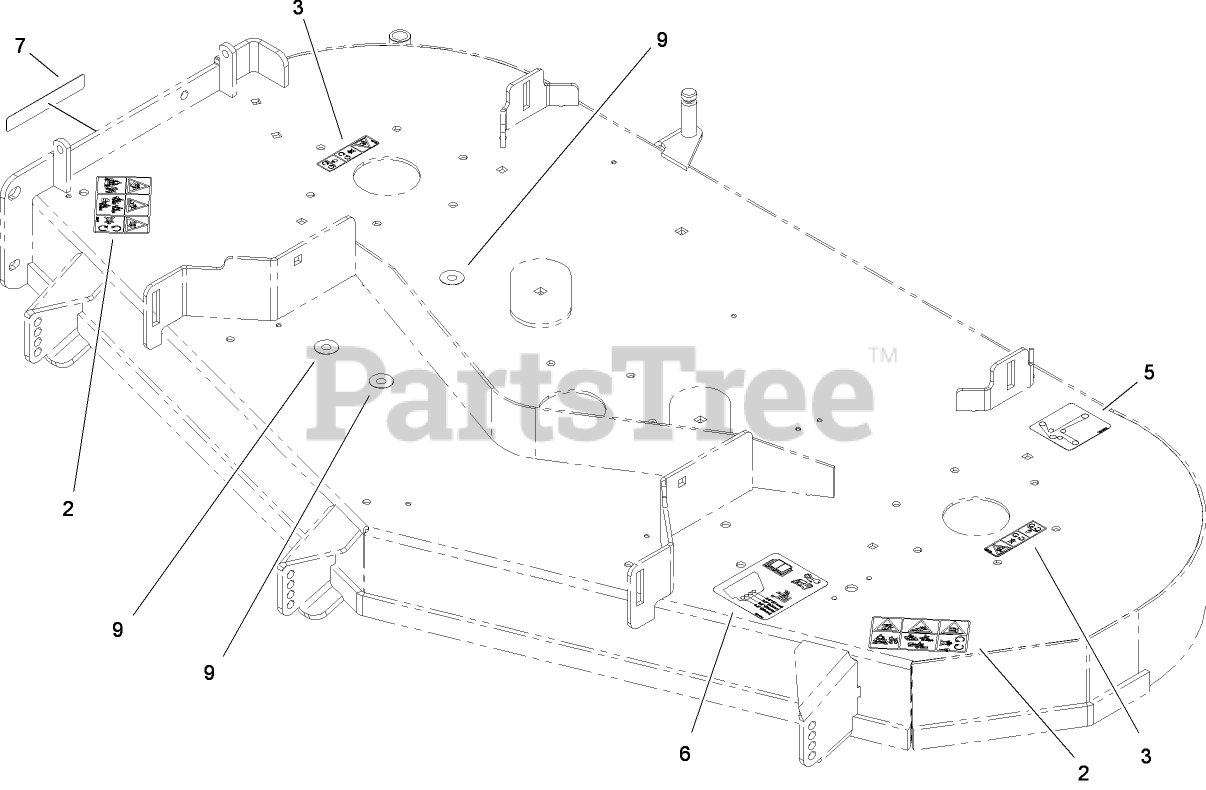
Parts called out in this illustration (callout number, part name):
2	DECAL-DANGER
3	DECAL-WARNING, BELT SHIELD
5	DECAL-ROUTING, BELT
6	DECAL-ROLLER, ANTI-SCALP
7	DECAL-DANGER
